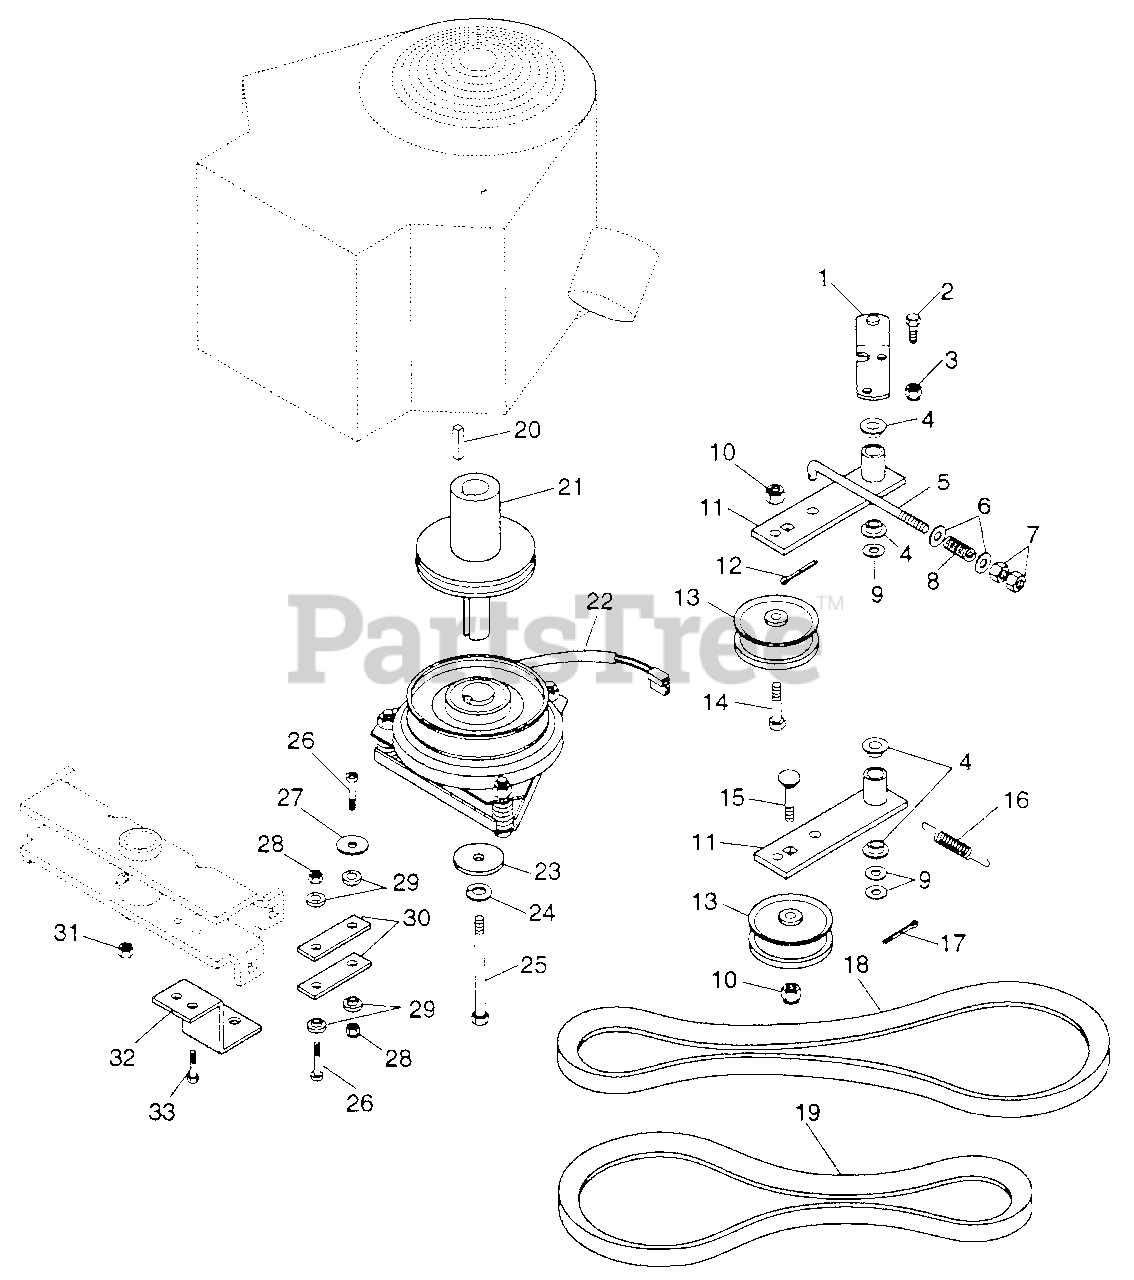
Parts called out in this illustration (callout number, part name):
2	Blt-Hex .31-18 .75 Pl Gr 5
3	Nut-Lk-Nyl .312-18 Pl
4	Bshg-Flg Ny .500 x .625 x .312 x .750
5	Rod
6	Wshr-Fl-Stl .406 x .812 x .065 Pl
7	Nut-Hex .375-16
8	Sg-Comp .188 x 1.66 x 2.0
9	Wshr-Fl-Stl .531 x 1.000 x .063
10	Nut-Lk-Nyl .375-16 Pl
11	Idler Arm
12	Pin-Cotr .09 x 1.0 Pl
13	Idler-Flat 2.75 x .38 Dayco
14	Blt-Hex .38-16 x 1.75 Pl Gr 5
15	Blt-Rdhdsqnk .38-16 x 1.75
16	Sg-Tens .087 x .55 x 6.13 Wld 10
17	Pin-Cotr .12 x 1.25 Pl
18	V-Belt
19	V-Belt
20	Key-Sg .248 x 1.0 x .248
21	Extension Shaft
22	Electric Clutch
23	Wshr-Special .469 x 2.000 x .250
24	Wshr-Lock .438 x .133 Hvy
25	Blt-Hex .44-20 x 5.50 Pl Gr 5
26	Scr-Mch 10-24 x 1.00 Phcr
27	Wshr-Fl-Stl .281 x 1.250 x .062 Pl
28	Nut-Lk 10-24 Ny Pl
29	Special Washer
30	Link
31	Nut-Lk-Nyl .250-20 Pl
32	Torque Bracket
33	Blt-Hex .25-20 x .75 Pl Gr 5
